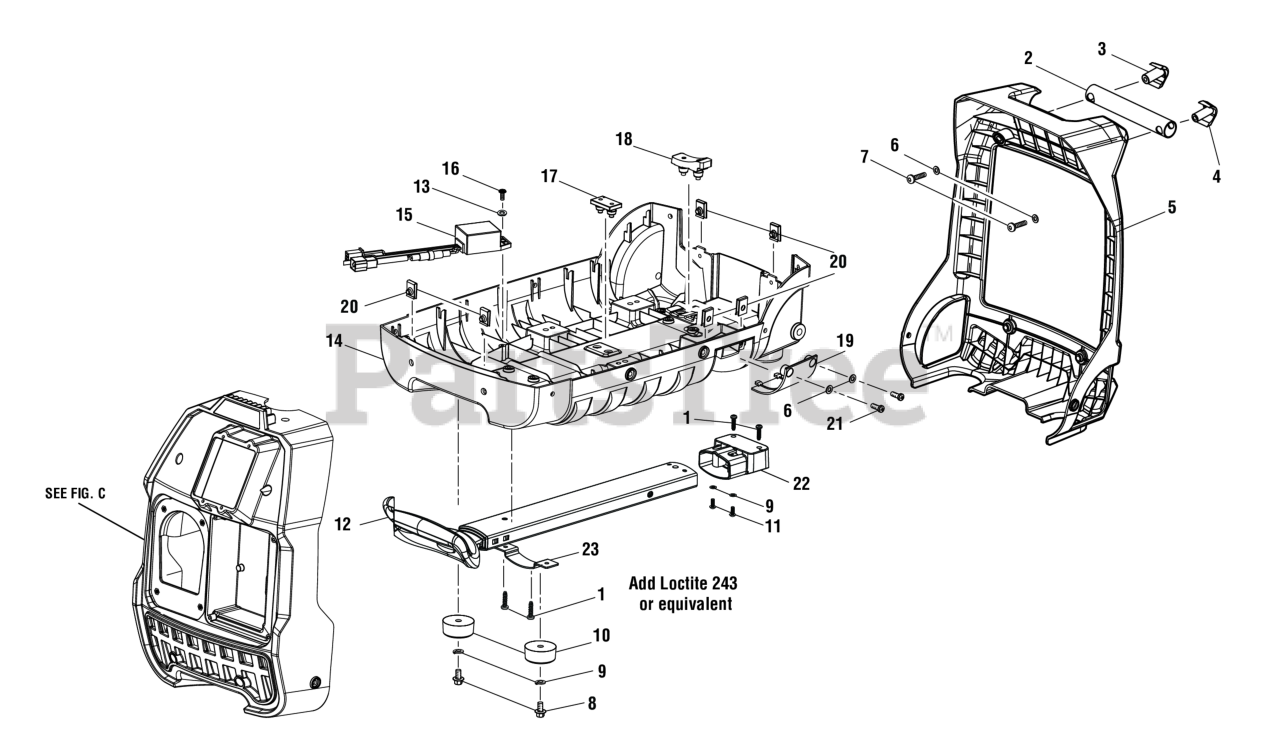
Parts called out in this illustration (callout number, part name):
1	Screw (M4.2 x 15 mm, Phillips Hd. S.T.)
2	Handle Tube
3	Handle Cap (Right)
4	Handle Cap (Left)
5	Rear Panel
6	Washer (ID5.3 x OD10 x 1t)
7	Screw (M5 x 20 mm, Button Soc. Hd.)
8	Bolt (M6 x 12 mm, Hex Hd.)
9	Lock Washer (1/4 in.)
10	Isolator Foot
11	Screw (M5 x 12 mm, T25 Torx Pan Hd.)
12	Retractable Handle Assembly
13	Washer (ID5.3 x OD10 x 1t)
14	Bottom Base
15	Regulator (AC to DC)
16	Screw (M4 x 16 mm, T20 Torx Socket Pan Hd.)
17	Engine Support Isolator (Front)
18	Engine Support Isolator (Back)
19	Oil Drain Door
20	U-Clip (M5)
21	Screw (M5 x 12 mm, Phillips Pan Hd)
22	Handle Bracket (Plastic)
23	Metal Bracket
